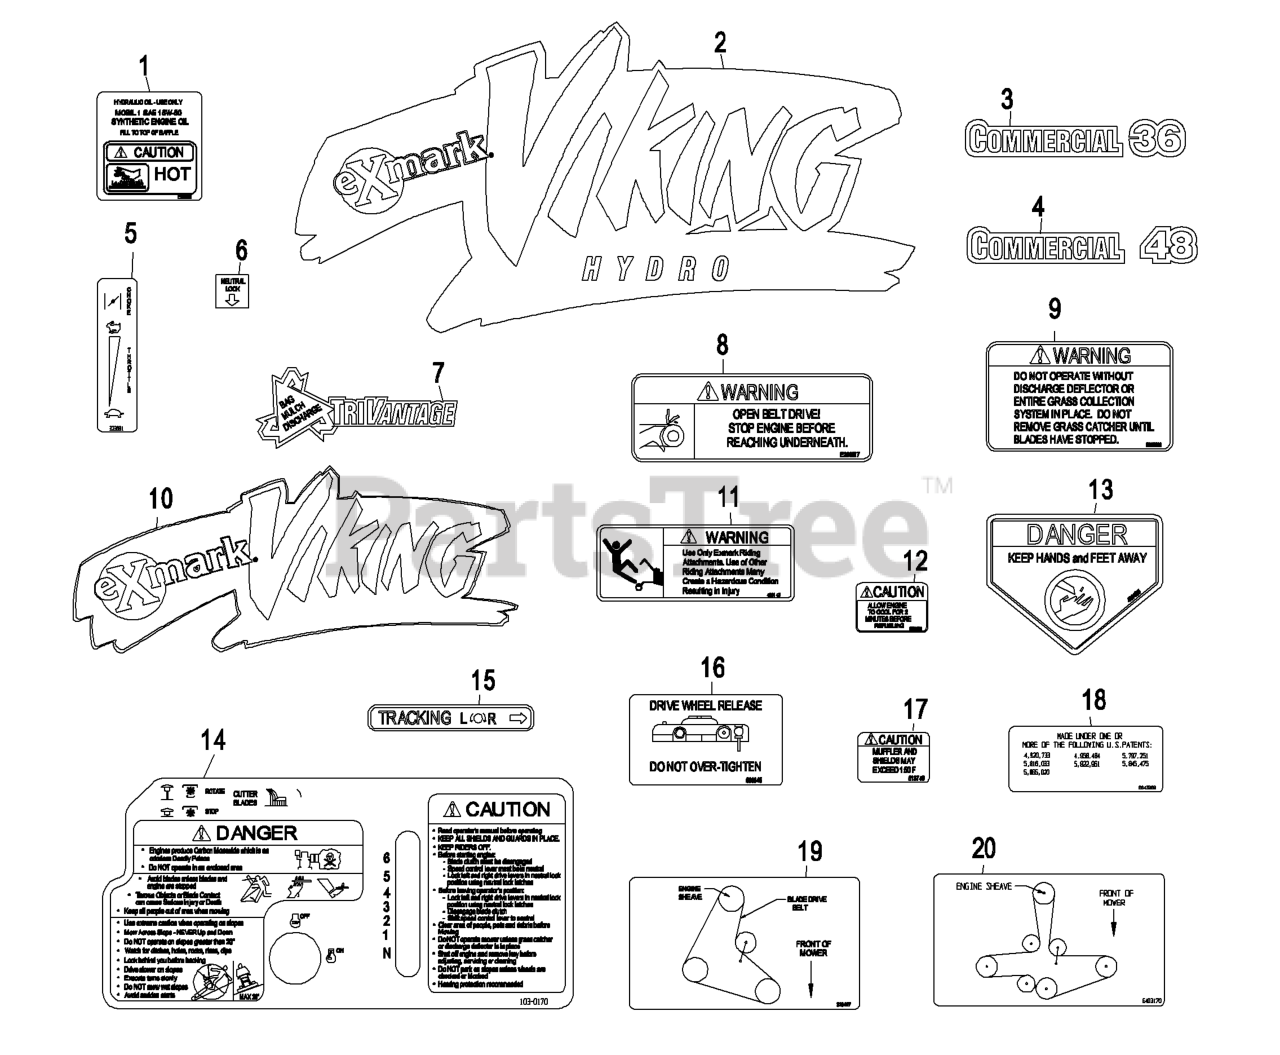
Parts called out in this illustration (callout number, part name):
3	DECAL,COMMERCIAL 36
4	DECAL,COMMERCIAL 48
5	DECAL,THROTTLE
6	DECAL,NEUTRAL LOCK
8	DECAL,BELT DRIVE
9	DECAL-WARNING, DISCHARGE
11	DECAL,SULKY WARNING
13	DECAL-DANGER
15	DECAL,TRACKING ADJUST
16	DECAL,DRIVE RELEASE
19	DECAL,BELT ROUTING 32/36
